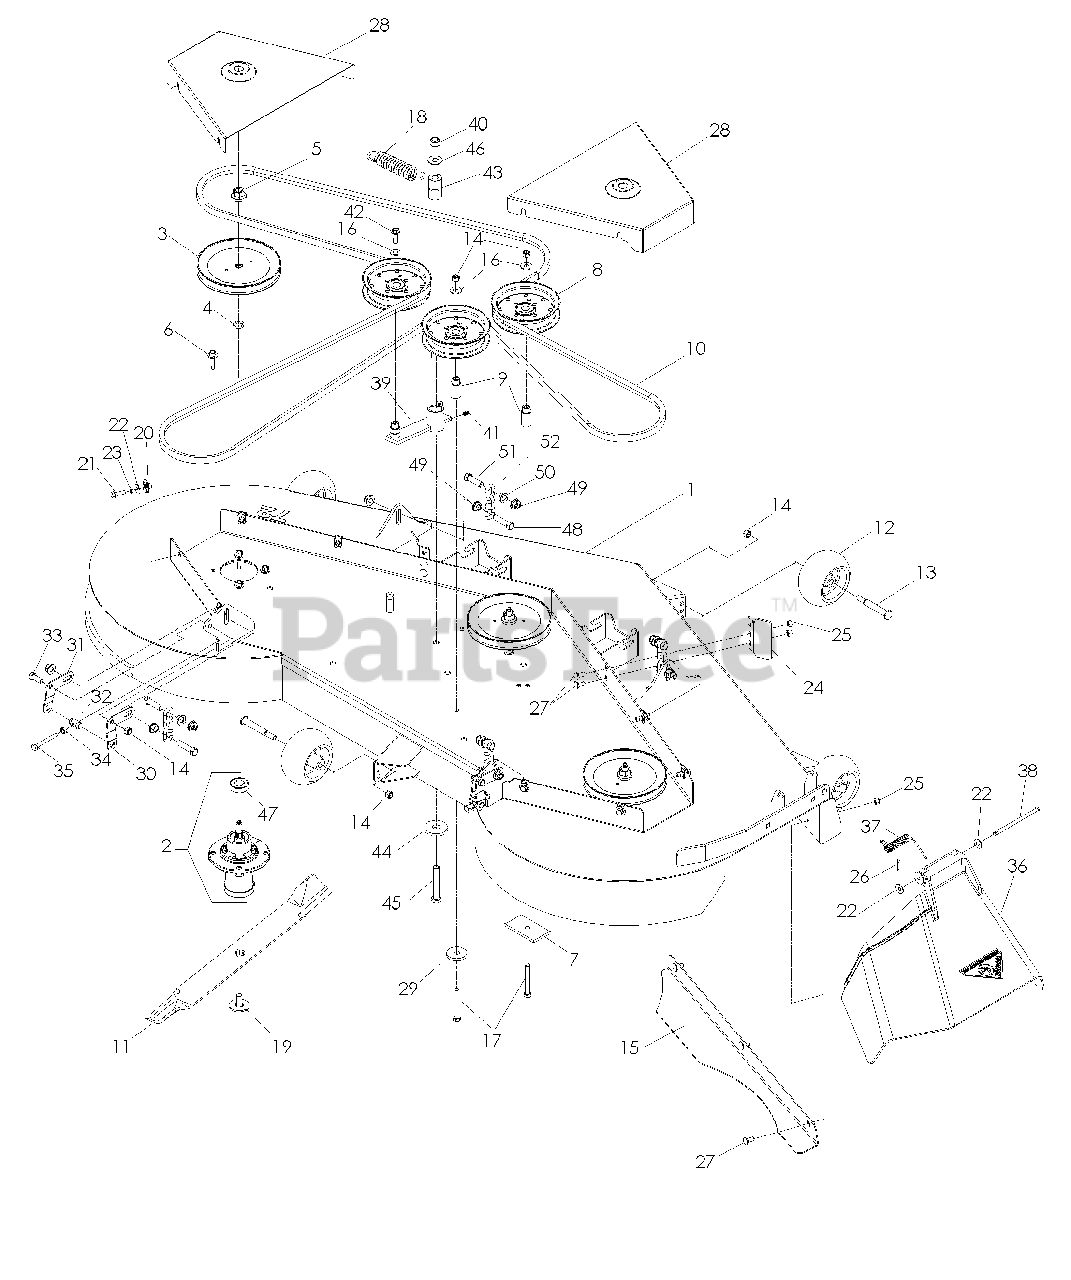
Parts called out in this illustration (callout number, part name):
1	DECK W/DECALS, 72" DIX
2	MANDREL.DECK.ASSEMBLY
4	WASHER-SPACER
5	LOCKNUT - 9/16
6	WASHER HEAD SCREW
7	SUPPORT PLATE
8	PULLEY, IDLER
9	IDLER BUSHING
10	BELT, DECK
11	BLADE, 25"
12	GAUGE WHEEL
13	SHOULDER BOLT 1/2X2-5/8 ZD SPE
14	NUT 3/8-16 NYLOC
15	CONFINEMENT PLATE, 72"
16	WASHER 3/8 FLAT
17	HCS 3/8C X 3
19	BLADE BOLT ASSY-7/16" TB REPL
20	U-CLIP 5/16-18 NUT RETAINER
21	HCS 5/16C X 1
22	WASHER 5/16 FLAT
23	WASHER 5/16 LOCK
24	DECK STOP
25	NUT 5/16 NYLOC
26	COTTER PIN 1/8 X 3/4
27	BOLT 5/16C X 3/4" CARRIAGE
28	SHIELD, BELT - 72" BLUE
29	SPINDLE WASHER
30	PITCH, ADJUST, RT
31	PITCH, ADJUST, LT
32	TRUNION, PITCH
33	HCS 3/8C X 1
34	NUT 5/16C HEX
35	HCS 5/16-18 X 2 1/2 TPBLT
36	DISCHARGE CHUTE - 72"
37	SPRING - TORSION
38	PIN-CLEVIS 5/16 DIA X 5.19 ZD
39	IDLER ARM
40	NUT 1/2-13 HEX NYLOC ZD
41	ZERK
42	HCS 3/8C X 1 SERRATED HEAD
43	PIVOT BUSHING
44	WASHER, SUPPORT
45	HCS 1/2C X 3 1/4
46	WASHER 1/2 FLAT
47	BAFFLE LEFT 54
48	HCS 7/16 - 14 X 1 3/4
49	NUT 7/16-14 HEX WHIZ LK
50	NUT 7/16C WHIZ
51	HCS 7/16C X 1 1/2
52	LIFT CHAIN - 3 LINK
